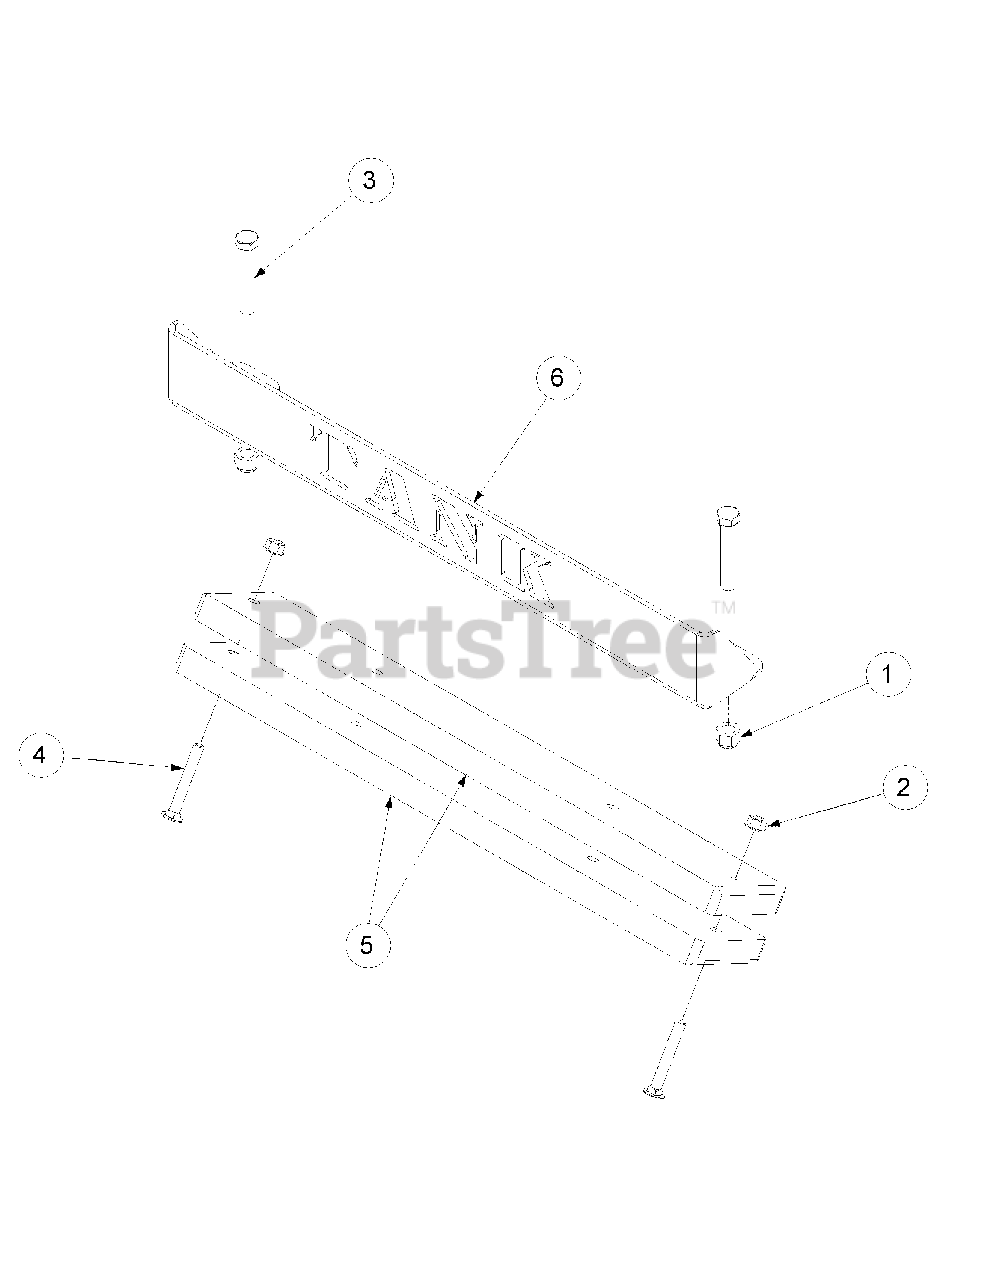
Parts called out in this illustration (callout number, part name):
1	Hex Nut, 1/2-13, Insert Lock
2	Nut, Hex 3/8-16 Flange Lock
3	HHCS, 1/2-13, 3.00
4	Carriage Bolt, 3/8-16 x 2.75
5	Bar, Weight
6	Rear Bumper Plate
